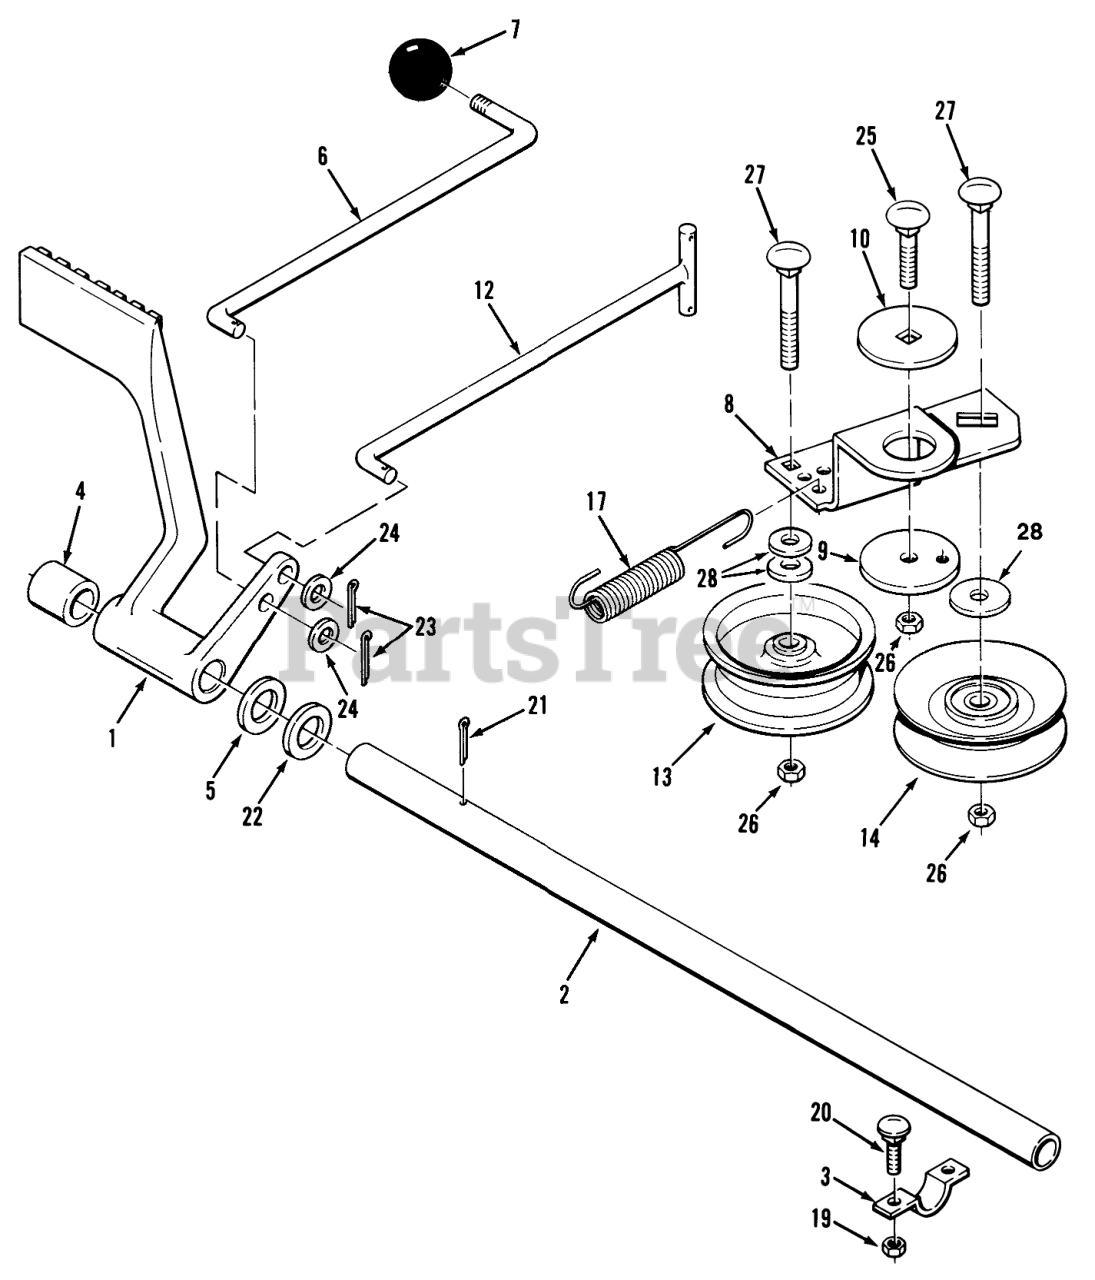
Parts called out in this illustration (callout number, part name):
1	PEDAL-BRAKE R
2	SHAFT PEDAL
3	CLAMP
4	SPACER
5	WASHER-WAVE
6	ROD-BRAKE LOCK B
7	KNOB
8	ARM-IDLER R
9	BUSHING
10	WASHER-BEARING
12	ASSY-ROD FRONT BR
13	PULLEY IDLER
14	PULLEY-IDLER
17	SPRING
19	NUT-LOCK, NI
20	BOLT-CARR
21	PIN-COTTER
22	Washer
23	PIN-COTTER
24	WASHER-PLAIN
25	BOLT-CARR
26	NUT-LOCK, NI
27	SCREW-CARR
28	WASHER-FLAT
29	WASHER-FLAT
